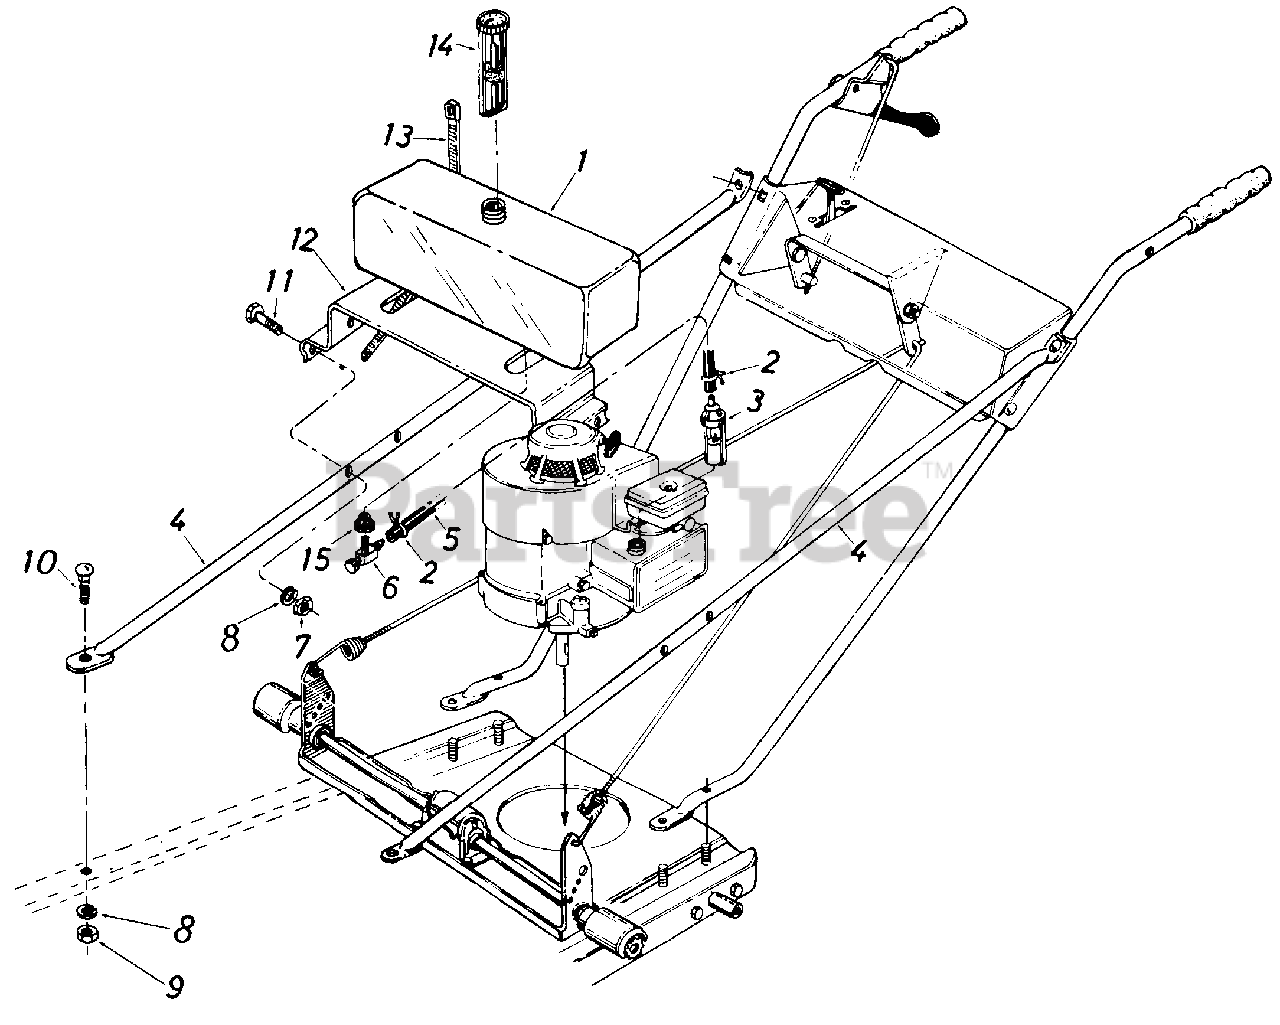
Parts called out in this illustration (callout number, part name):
1	Fuel Tank
2	Hose Clamp 3/8 I.D.
3	Fuel Control Valve
4	Strut
5	Fuel Line
6	Fuel Tank Fitting
7	Hex Nut 5/16-24" Thd.
8	L-Wash. 5/16" I.D.
9	Hex Nut 5/16-18" Thd.
10	Carriage Bolt 5/16-18 x .62" Lg.
11	Hex Bolt 5/16-24 x 1.25" Lg.
12	Fuel Tank Mntg. Brk't.
13	Cable Tie 30.6" Lg.
14	Fuel Gauge
15	Bushing
